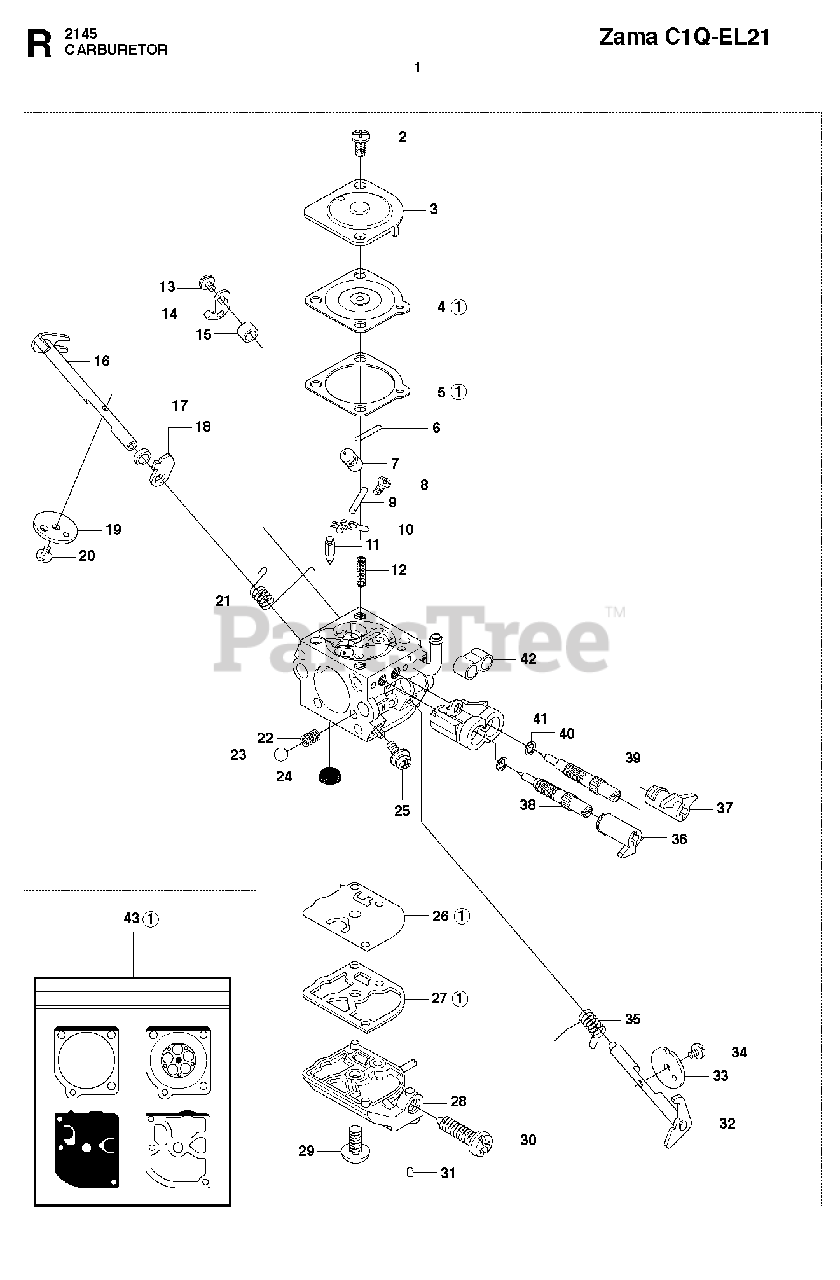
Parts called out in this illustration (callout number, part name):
1	CARBURETOR
2	SCREW
3	COVER
4	METERING DIAPHRAGM
5	GASKET METERING SIDE
6	PLUG
7	SPREADER
8	SCREW
9	PIN FULCRUM
10	LEVER
11	INLET NEEDLE
12	SPRING
13	SCREW
14	LEVER
15	SPACER
16	CHOKE SHAFT
17	BUSHING *
18	LEVER
19	DISC
20	SCREW
21	SPRING
22	SPRING
23	BALL
24	STRAINER
25	SCREW *
26	PUMP DIAPHRAGM
27	GASKET
28	COVER
29	SCREW
30	SCREW
31	PLUG
32	THROTTLE SHAFT
33	THROTTLE FLAP
34	SCREW
35	SPRING
36	LIMITER CAP
37	LIMITER CAP
38	NEEDLE HIGH SPEED
39	NEEDLE LOW SPEED
40	WASHER
41	SLEEVE
42	SLEEVE
43	GASKET SET
